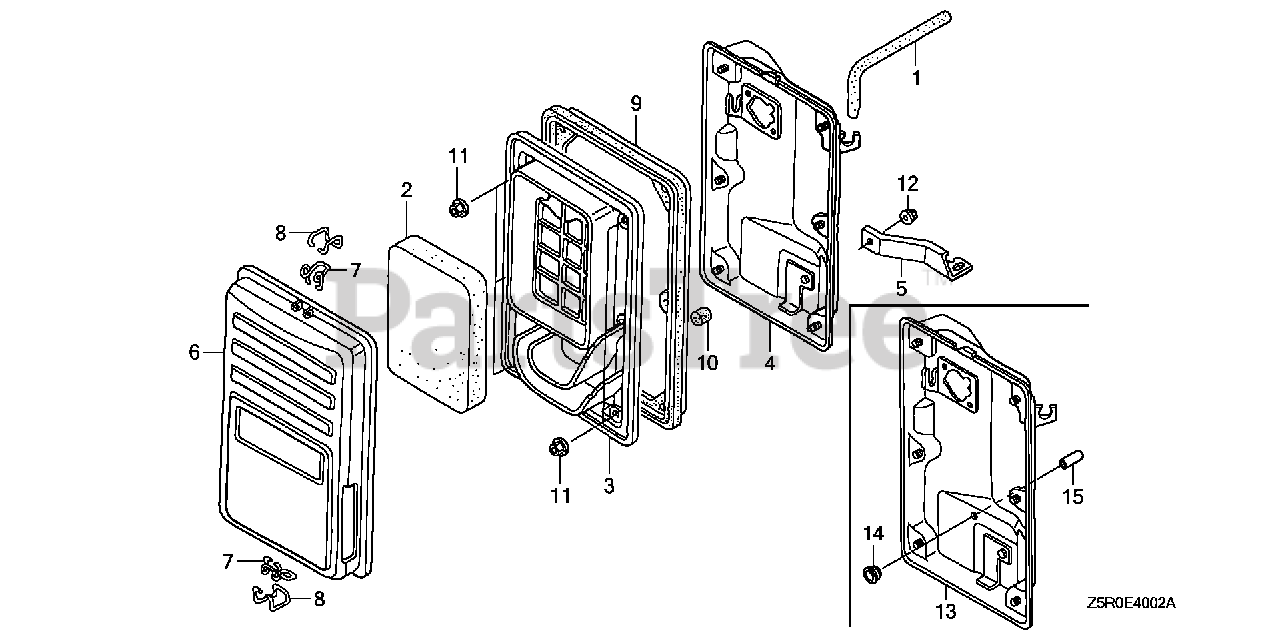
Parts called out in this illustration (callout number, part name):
1	TUBE, BREATHER
2	ELEMENT, AIR CLEANER
3	SEPARATOR, AIR CLEANER
5	STAY, AIR CLEANER
6	COVER, AIR CLEANER
7	CLIP A, AIR CLEANER WIRE
8	CLIP B, AIR CLEANER WIRE
9	SEAL, AIR CLEANER
10	FILTER, DRAIN TUBE
11	NUT, FLANGE (5MM)
12	NUT, FLANGE (6MM)
13	HOUSING, AIR CLEANER
14	GROMMET, AIR CLEANER
15	CAP, SEALING
